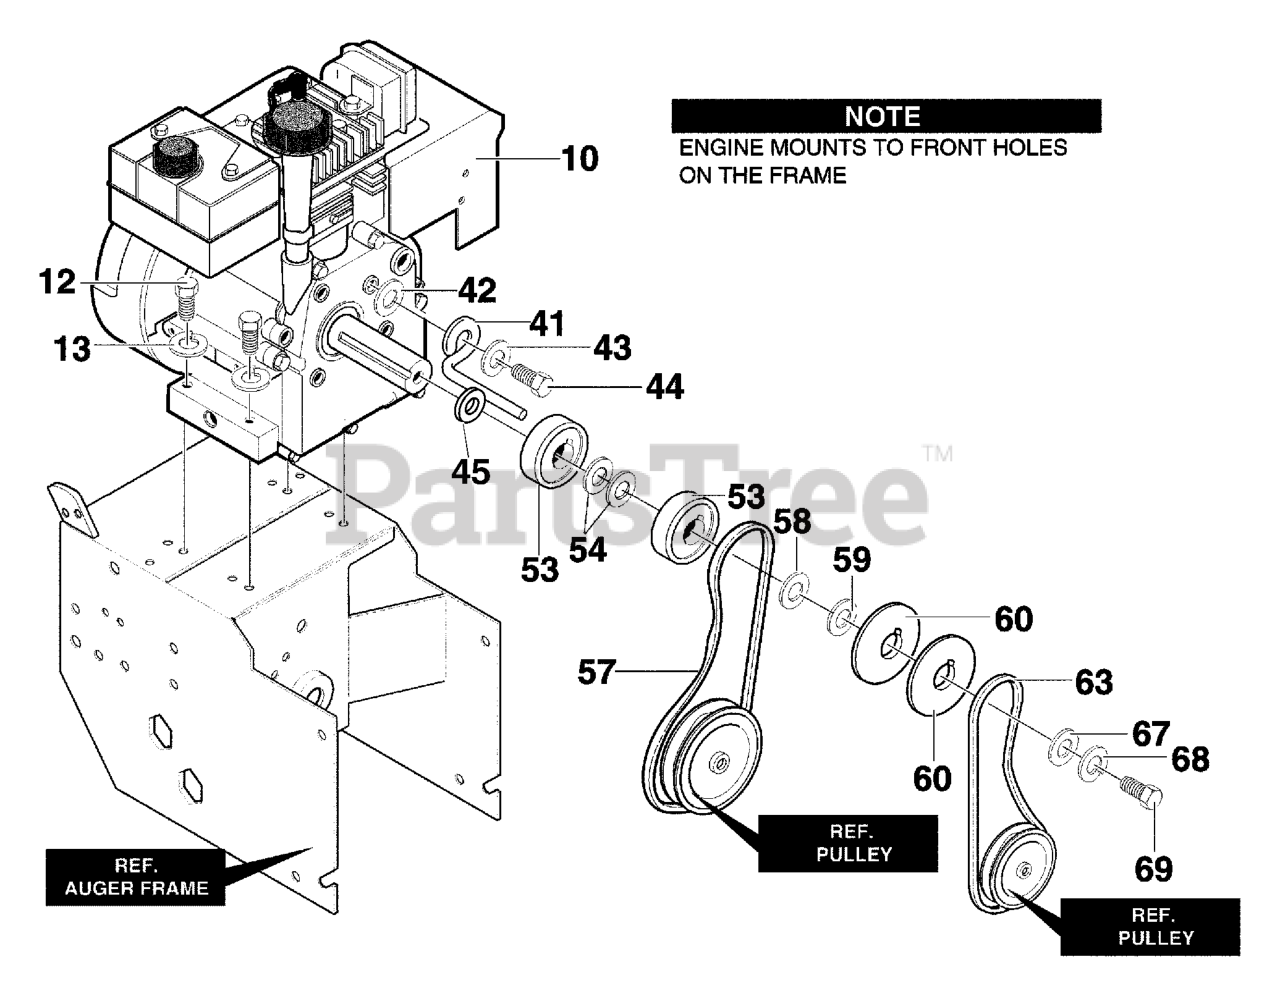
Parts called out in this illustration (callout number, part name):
10	ENGINE
12	SCREW, 5/16-18
13	WASHER, SPTLK .31X.58X.08
41	GUIDE, ROD BELT
42	PLASTIC WASHER
43	WASHER, SPTLK .31X.58X.08
44	SCREW, 5/16-24 x 1.00
53	PULLEY, HALF
54	WASHER, FLAT .752X.91X.02
57	BELT, V 3L 33.13LG
58	FLATWASHER .765X1.12X.06
59	SPACER, SLEEVE
60	PULLEY, ENGINE
63	BELT, V 4L38.1LG
67	WASHER, FLAT .375X1.25X.104
68	WASHER,HVSPTLK .38ID
69	SCREW, 3/8-24 x 1.00
